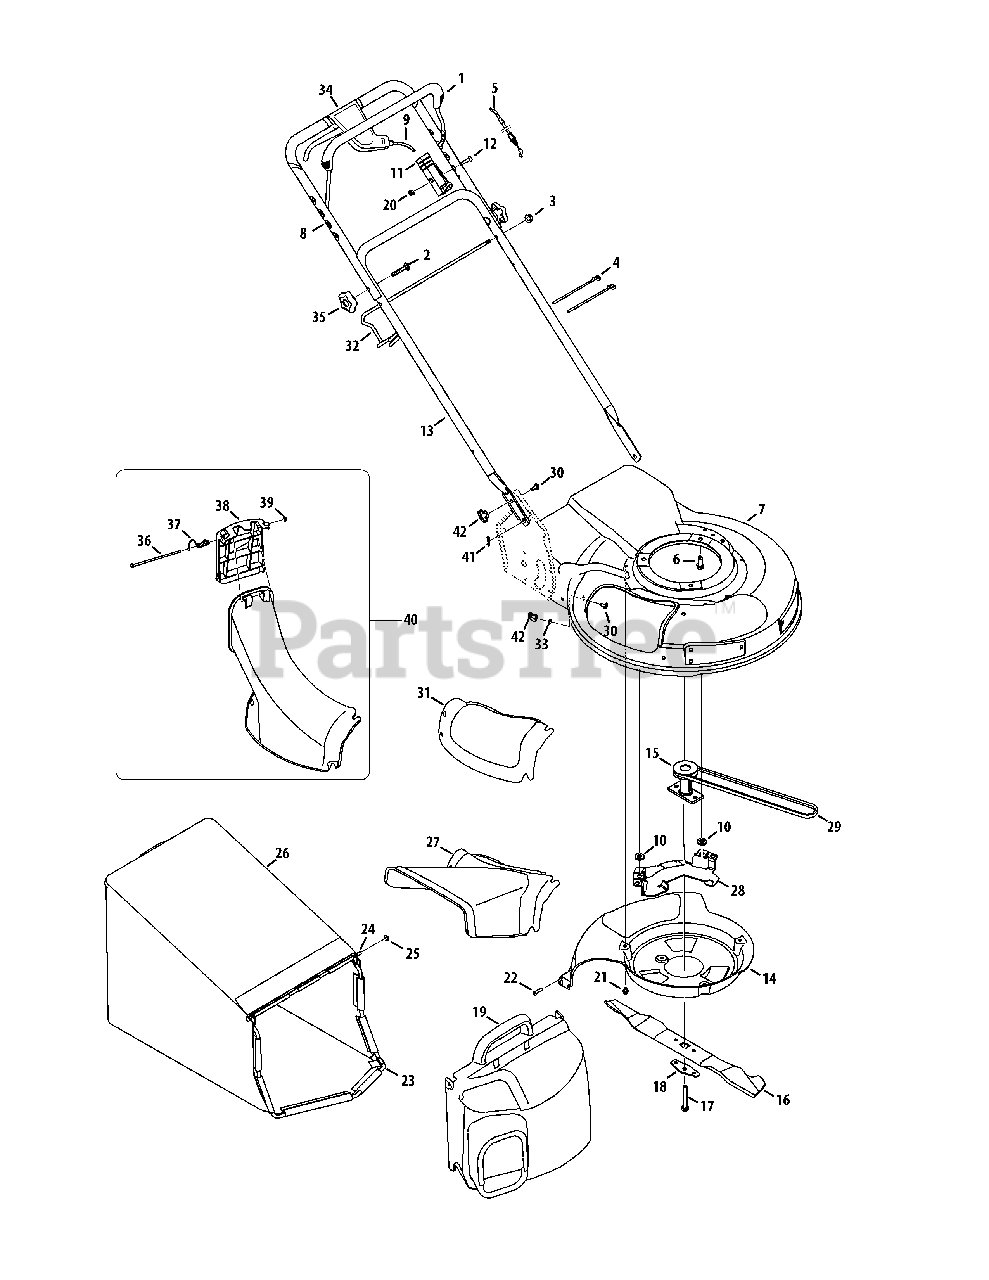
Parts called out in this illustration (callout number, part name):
1	Blade Control
2	Carriage Bolt 5/16-18 x 2
3	Flange Lock Nut, 5/16-18
4	Cable Tie
5	Control Cable
6	TT Screw, 3/8-16 x 1.00
9	Drive Cable
10	Washer, Flat, .407 x .812 x .135
11	Control Cable Mount
12	Screw, 1/4-20 x 1.310
14	Engine Baffle
15	Blade Adapter
16	21-inch Mulching Blade
17	HH Cap Screw, 3/8-24 x 2.50
18	Bell Blade Spacer
19	Grass Bag Cover Assembly
20	Hex Lock Nut 1/4-20
21	TT Screw 1/4-20 x .375
22	HL Screw 1/4-15 x .75
23	Grass Bag Frame
24	Grass Bag Pivot Rod
25	Cap Speed Nut
26	Grass Bag
27	Side Discharge Chute
28	Belt Keeper
30	Carriage Screw 1/4-20 x .75
31	Mulch Cover
32	Grass Bag Support Rod
34	Drive Control Assembly
36	Chute Door Pivot Rod
37	Torsion Spring
38	Top Discharge Door Chute
40	Top Discharge Chute Assembly
41	Cotter Pin
42	Wing Nut
